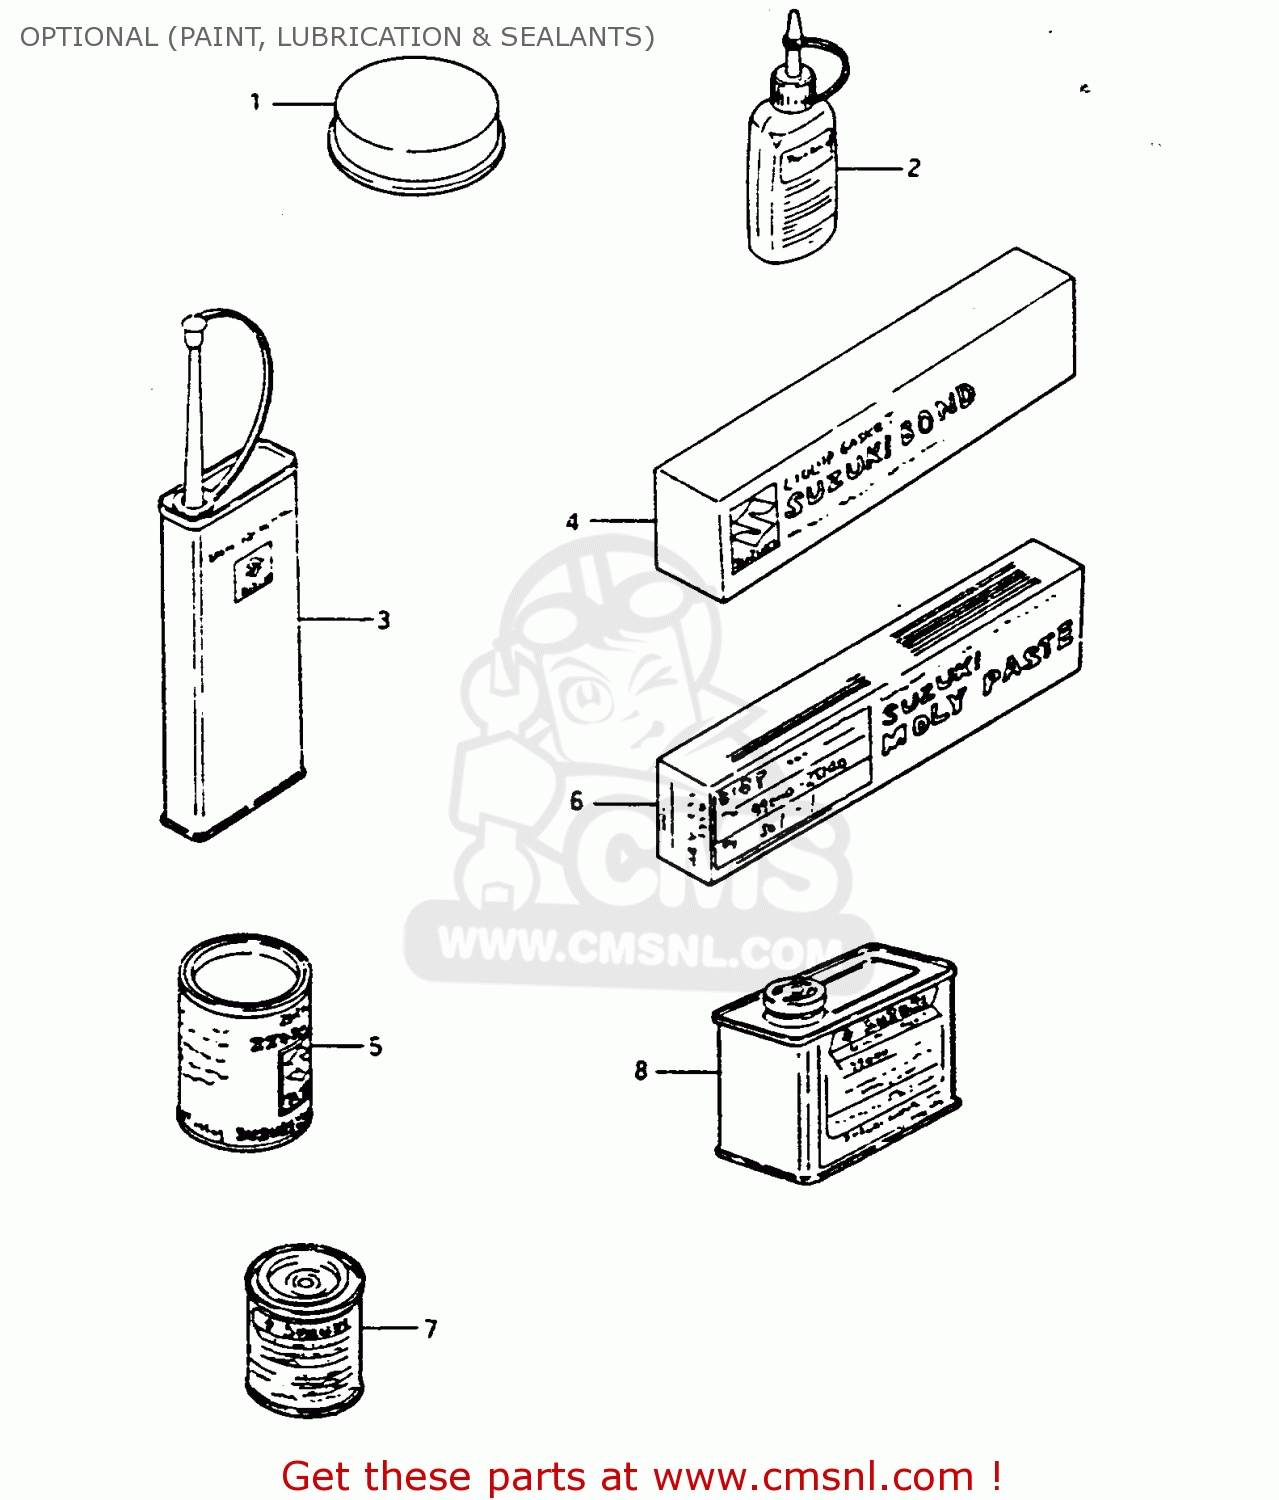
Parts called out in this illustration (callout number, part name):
1	GREASE,PBC FOR BRK PAD 20G
2	THREAD LOCK NO.1342
3	THREAD LOCK NO.1401 CLEAR 200G
4	SUZUKI BOND (1216)
5	GREASE(C)EP2 LITHIUM 150G
6	SUZUKI MOLY PASTE
7	PAINT,BLACK
8	PAINT (SPACE BLACK)
